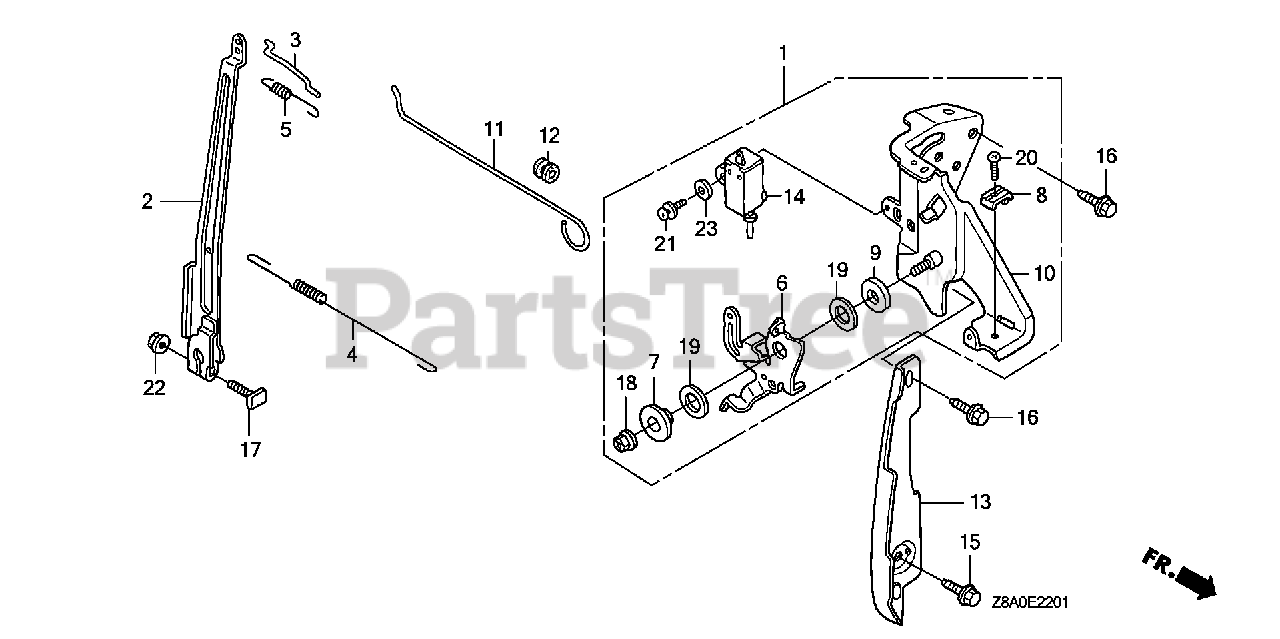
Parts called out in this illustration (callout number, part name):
1	CONTROL ASSY.
2	ARM, GOVERNOR
3	ROD, GOVERNOR
4	SPRING, GOVERNOR
5	SPRING, THROTTLE RETURN
6	LEVER, CONTROL
7	WASHER, CONTROL LEVER
8	HOLDER, CABLE
9	SPACER, CONTROL LEVER
10	BASE, CONTROL
11	ROD, CHOKE CONTROL
12	GROMMET, CHOKE ROD
13	PLATE, SIDE
14	SWITCH ASSY., ENGINE STOP (N.O)
15	BOLT, FLANGE (6X12) (CT200)
16	BOLT, FLANGE (6X14)
17	BOLT, GOVERNOR ARM
18	NUT, SELF-LOCK (6MM)
19	WASHER (12.5MM)
20	SCREW, PAN (5X16)
21	SCREW-WASHER (4X12)
22	NUT, FLANGE (6MM)
23	WASHER, PLAIN (4MM)
